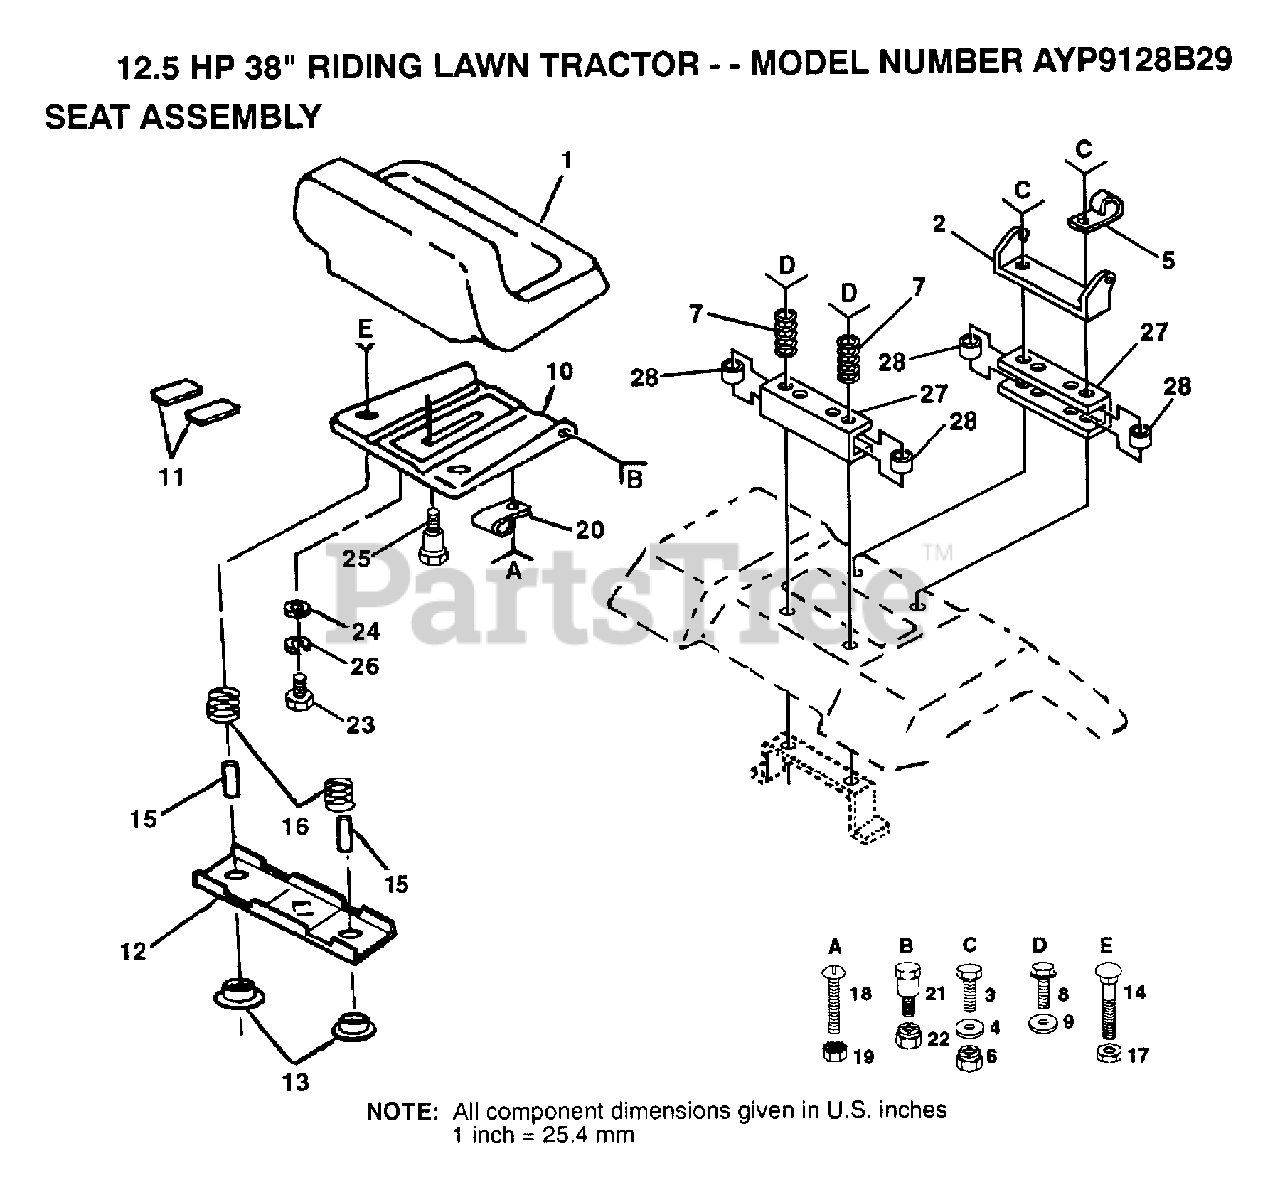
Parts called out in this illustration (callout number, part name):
1	SHAFT.PU.2003022
2	RETAINIANG RING-(2003016)
3	BALL BEARING
4	SPACER
5	SEAL LIP
6	RING.RET.2003052
8	CRADLE BEARING (2003023)
11	BEARING
12	SEAL.9008000-0126
13	TRUNION ARM (2003005)
14	GUIDE.2000015.HYD
18	PLUG PIPE
19	"KIT,CTR SECTION (2513007)"
20	NEEDLE BEARING
21	LIP SEAL-9008000-0127
22	SHAFT
25	"SWASHPLATE,VARIAB"
30	SEAL LIP
31	"KIT,BLOCK CYLINDE"
36	"PLUG,PLASTIC 9005200-8700"
37	PIN
38	GASKET.20030600
39	FILTER
40	WASHER (2000011)
41	SPRING
42	KIT.VALVE.2513014
46	PLUG
47	SCREW9007314-0808
50	WASHER
51	PIN
52	PLUG
55	"KIT,BYPASS VALVE"
58	PLUG
59	"KIT,OVERHEAD SEAL -2513013"
